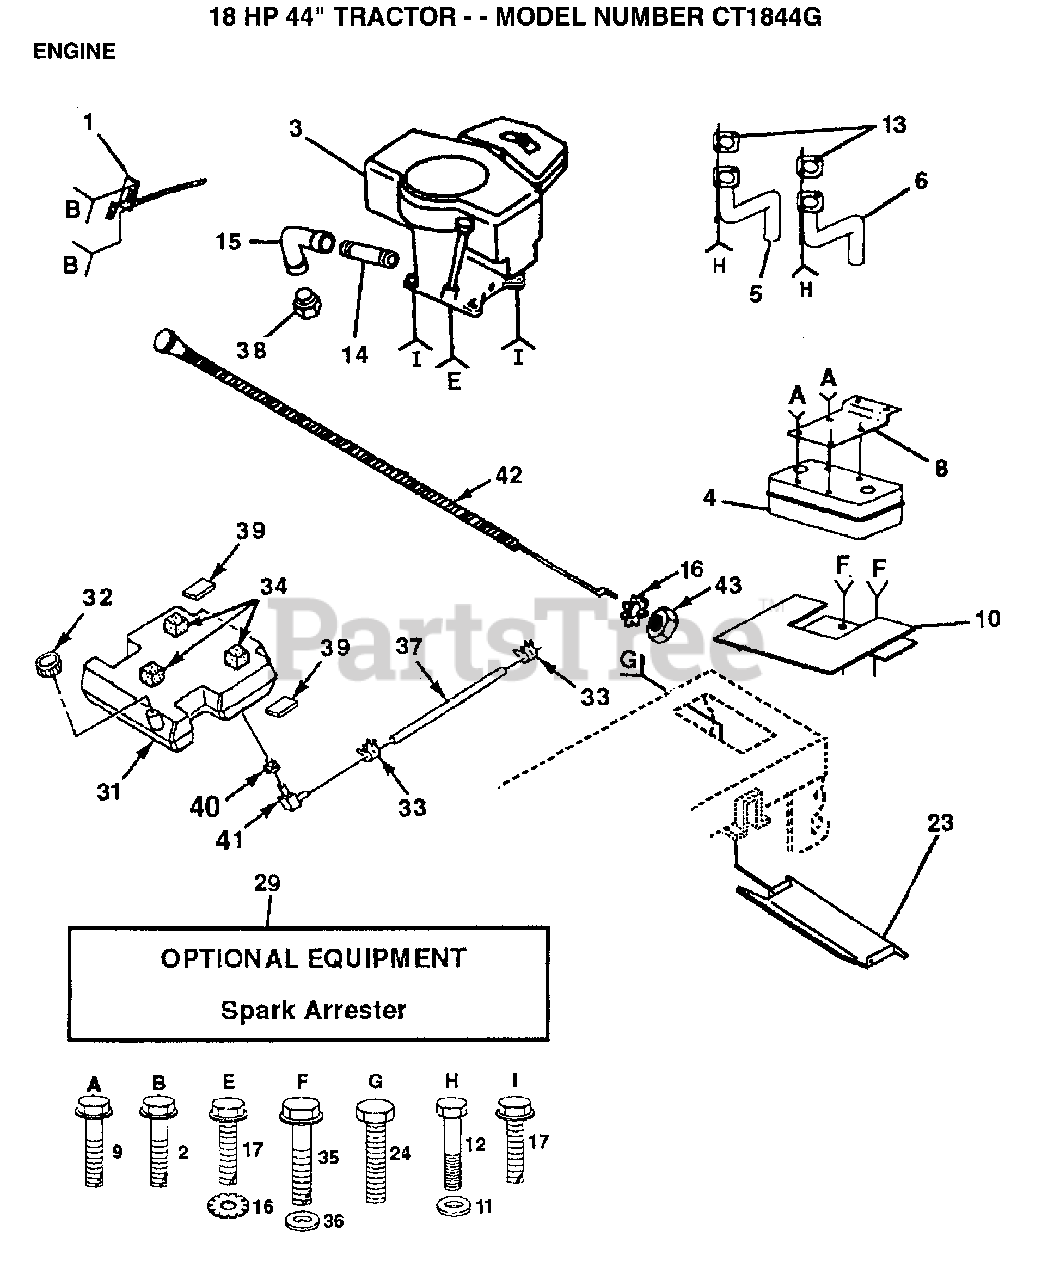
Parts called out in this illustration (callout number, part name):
2	SCREW LT
3	ENGINE B&S 18HP
5	EXHAUST ASM LH
8	BRACKET MUFFLER
9	SCREW ST
10	SHIELD HEAT LT
11	LOCKWASHER
14	PIPE NIPPLE LT
15	ELBOW
16	LOCKWASHER
17	SCREW LT
23	HEAT SHIELD
24	SCREW
32	CAP ASM FUEL
33	HOSE CLAMP
34	PAD-SPACER LT
35	SCREW
36	WASHER
37	FUEL LINE T
39	PAD IDLER TI
40	BUSHING OUTLET T
41	STEM.TANK.FUEL
42	CHOKE CONTROL
